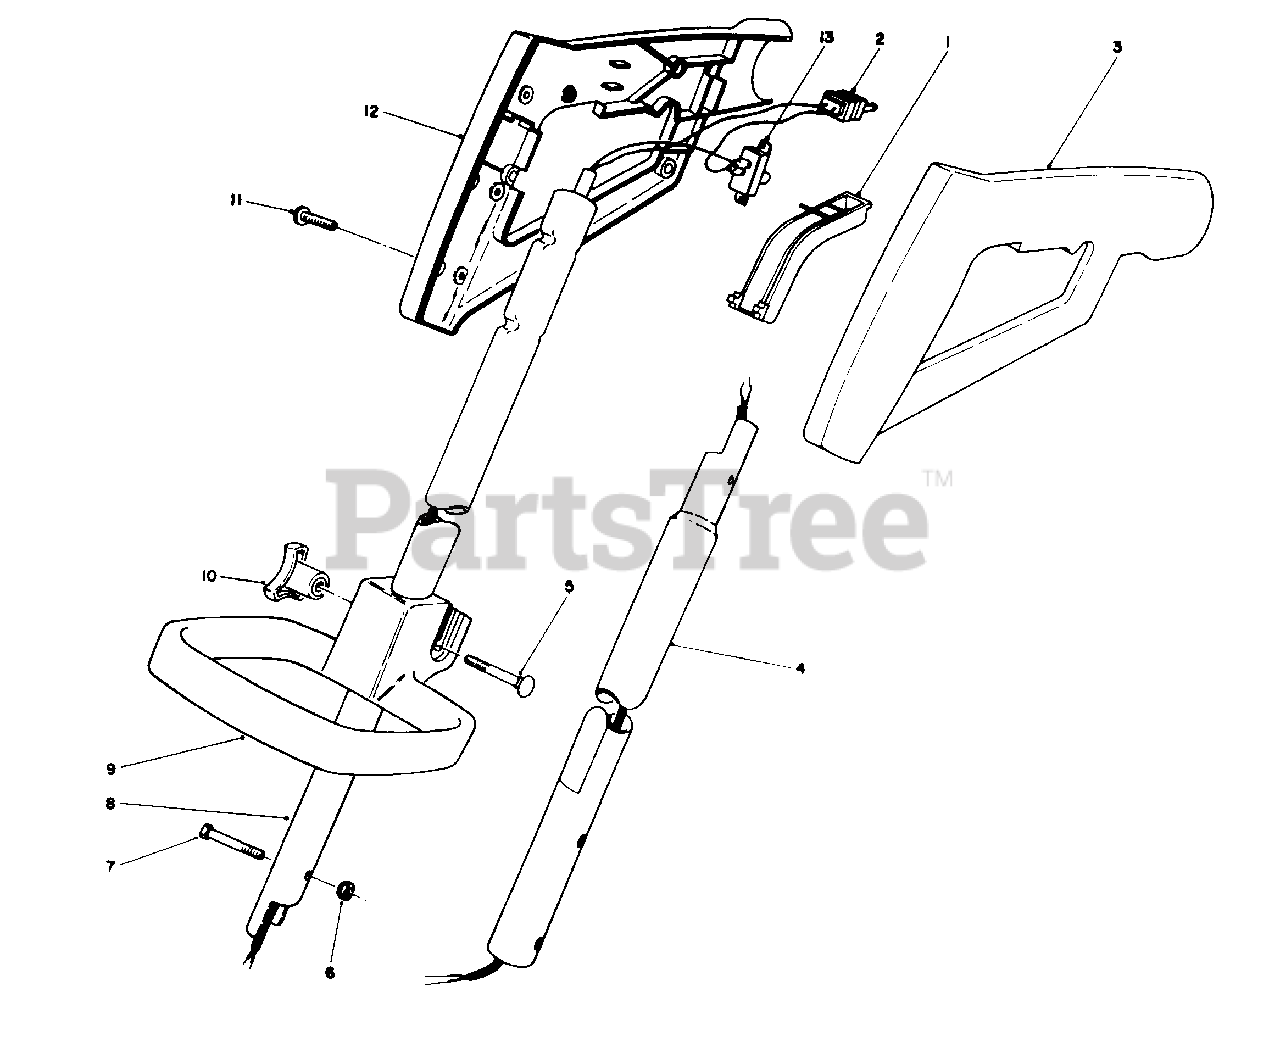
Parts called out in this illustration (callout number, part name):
1	Bar-Switch
2	Harness-Wiring
3	Grip-Left Handle
4	Tube-Lower
5	Bolt-Carriage
6	Nut-Lock
7	Screw-Machine
8	Tube-Upper
9	Handle-Adjustable
11	Screw
12	Grip-Right Handle
13	Switch-Single Speed
